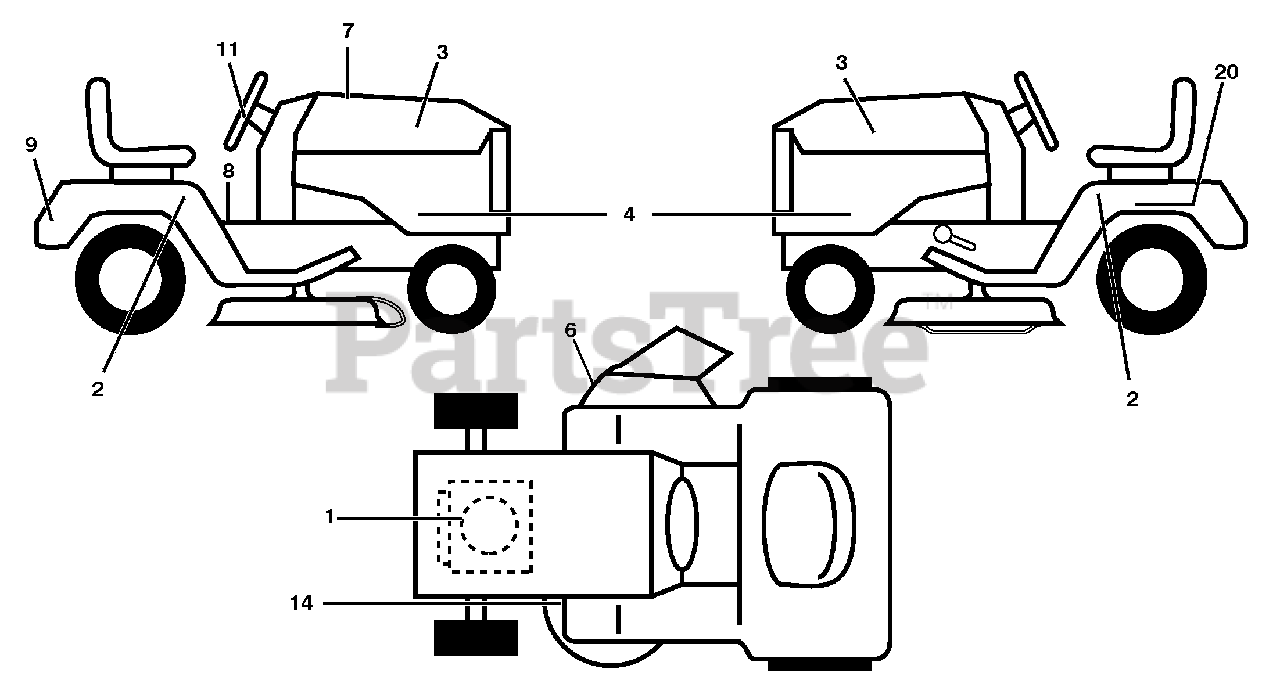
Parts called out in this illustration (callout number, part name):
1	Decal, Engine HP
2	Decal, Fender RH/LH
3	Decal, Hood
4	Decal, SDPNL.
6	Decal, Warning, Keep Hand Away
7	Decal, Replacement Parts
8	Decal, Fender Warn S/F
9	Decal, Fender Logo
11	Decal, Ins Strg Whl
14	Decal, V-Belt Schematic
20	Decal, Bat Dan/Psn
20	Pad Footrest LH
20	Pad Footrest RH
20	Manual Operator's (English/French)
20	Manual Operator's (Spanish)
20	Manual Parts (English)
